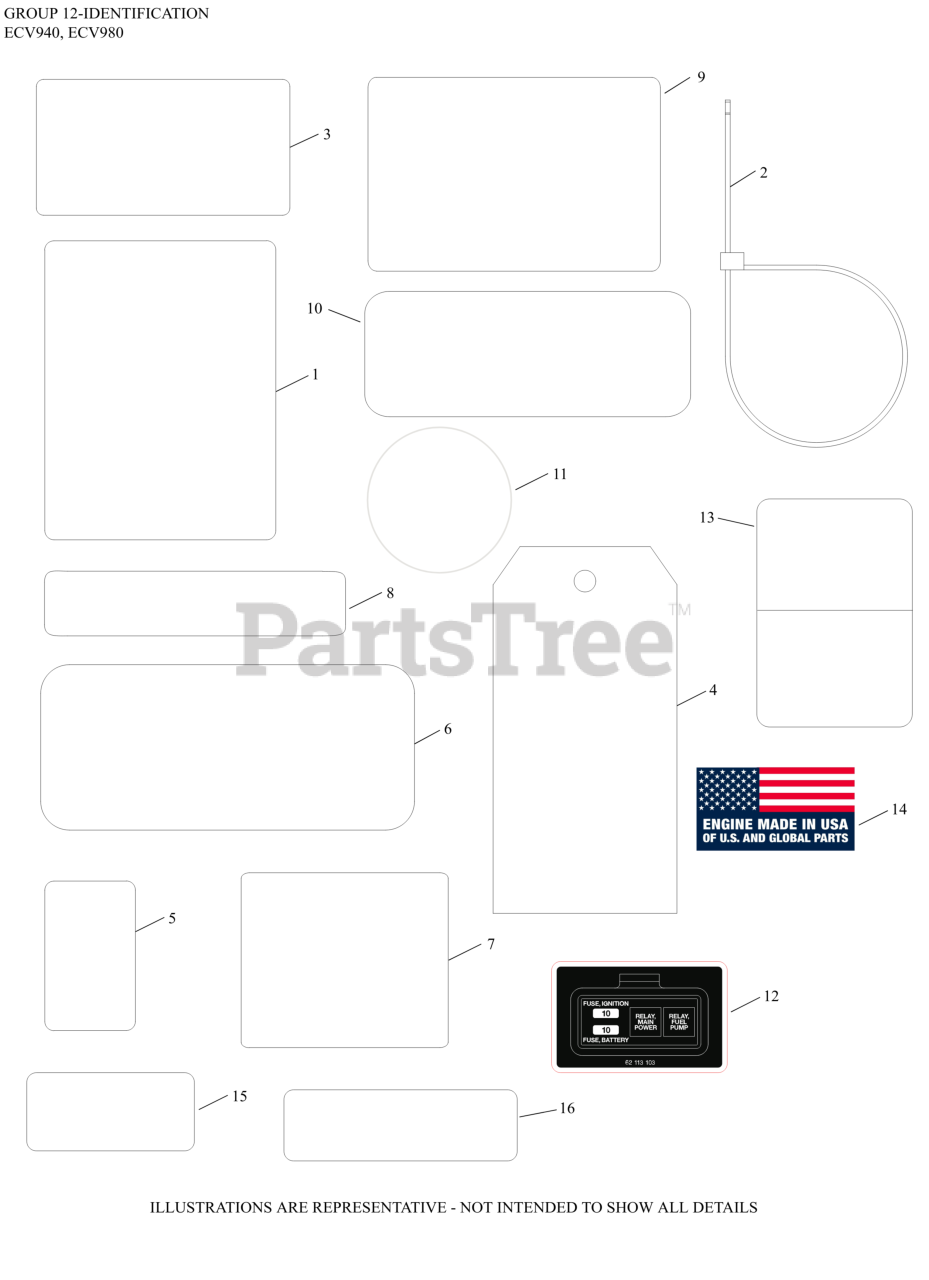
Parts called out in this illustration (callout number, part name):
1	LABEL, CLEAR LAMINATION
5	DECAL - DISCONTINUED
7	DECAL HDAC, ECV940/999cc
8	LABEL, GCU FIXED JOINT
9	LABEL, OIL RECOMMENDATION
